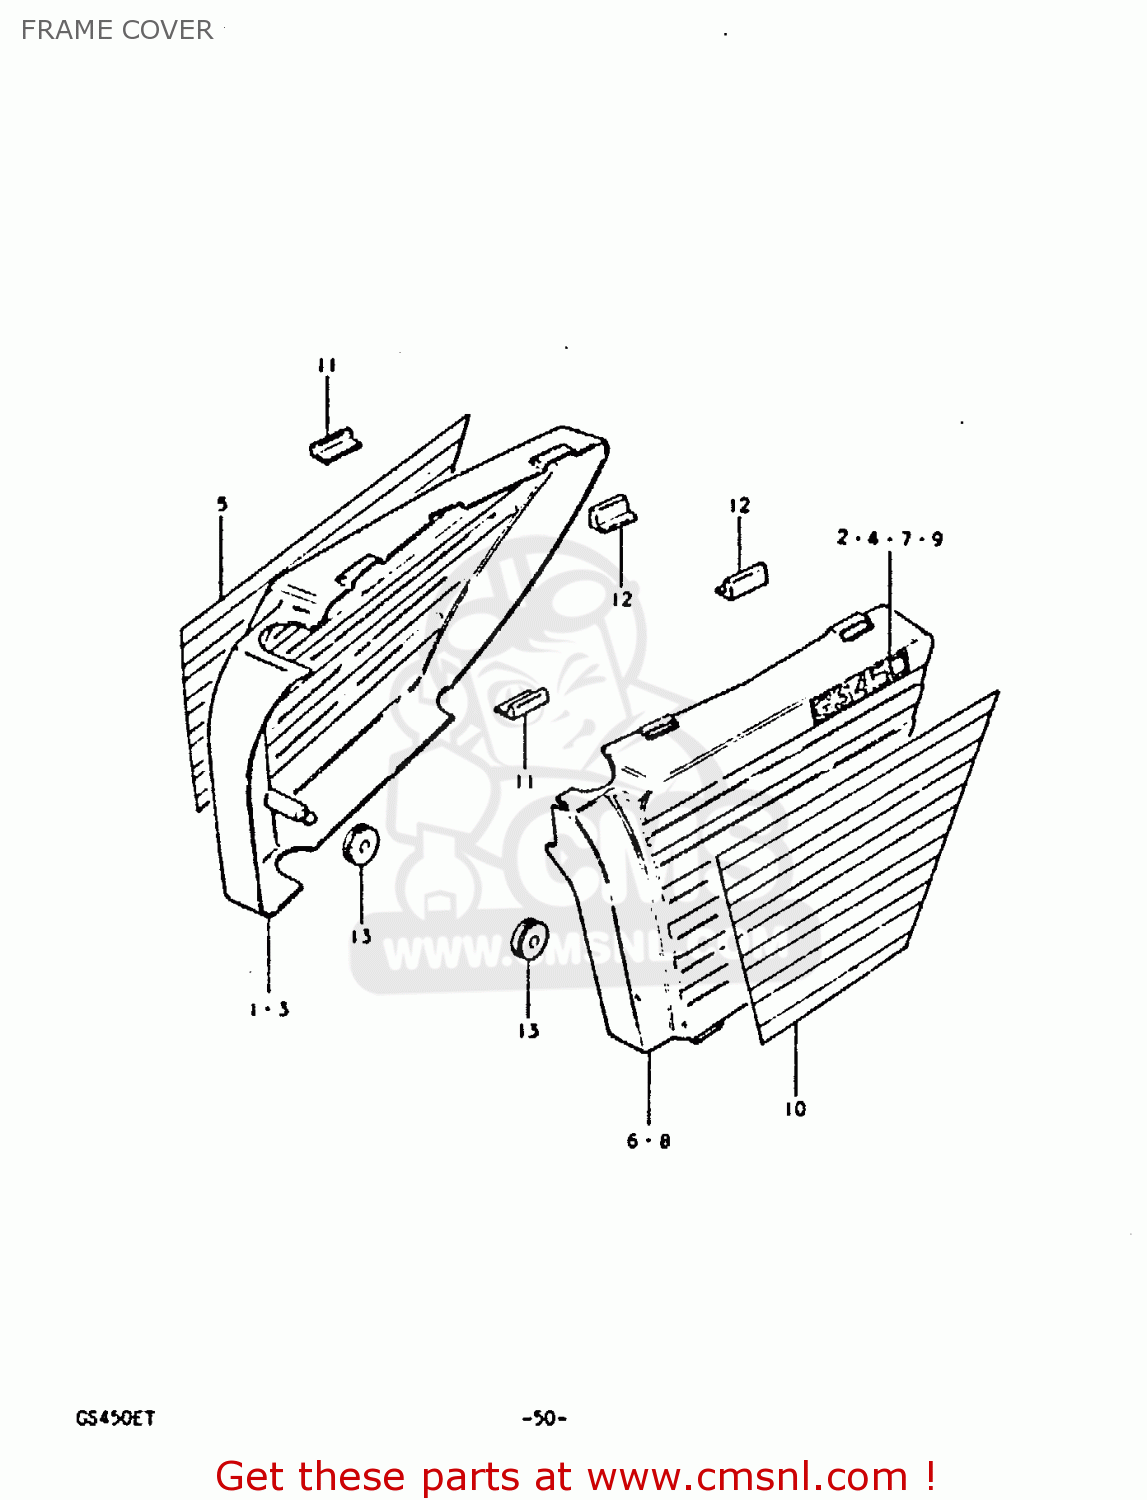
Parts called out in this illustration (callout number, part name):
1	COVER,FRAME,RIGHT
2	EMBLEM (450)
3	COVER,FRAME,RIGHT
4	EMBLEM (450)
5	TAPE SET, RH
6	COVER,FRAME,LEFT
7	EMBLEM (450)
8	COVER,FRAME,LEFT
9	EMBLEM (450)
10	TAPE SET
11	CUSHION,FRAME COVER
12	CUSHION,FRAME COVER
13	CUSHION
